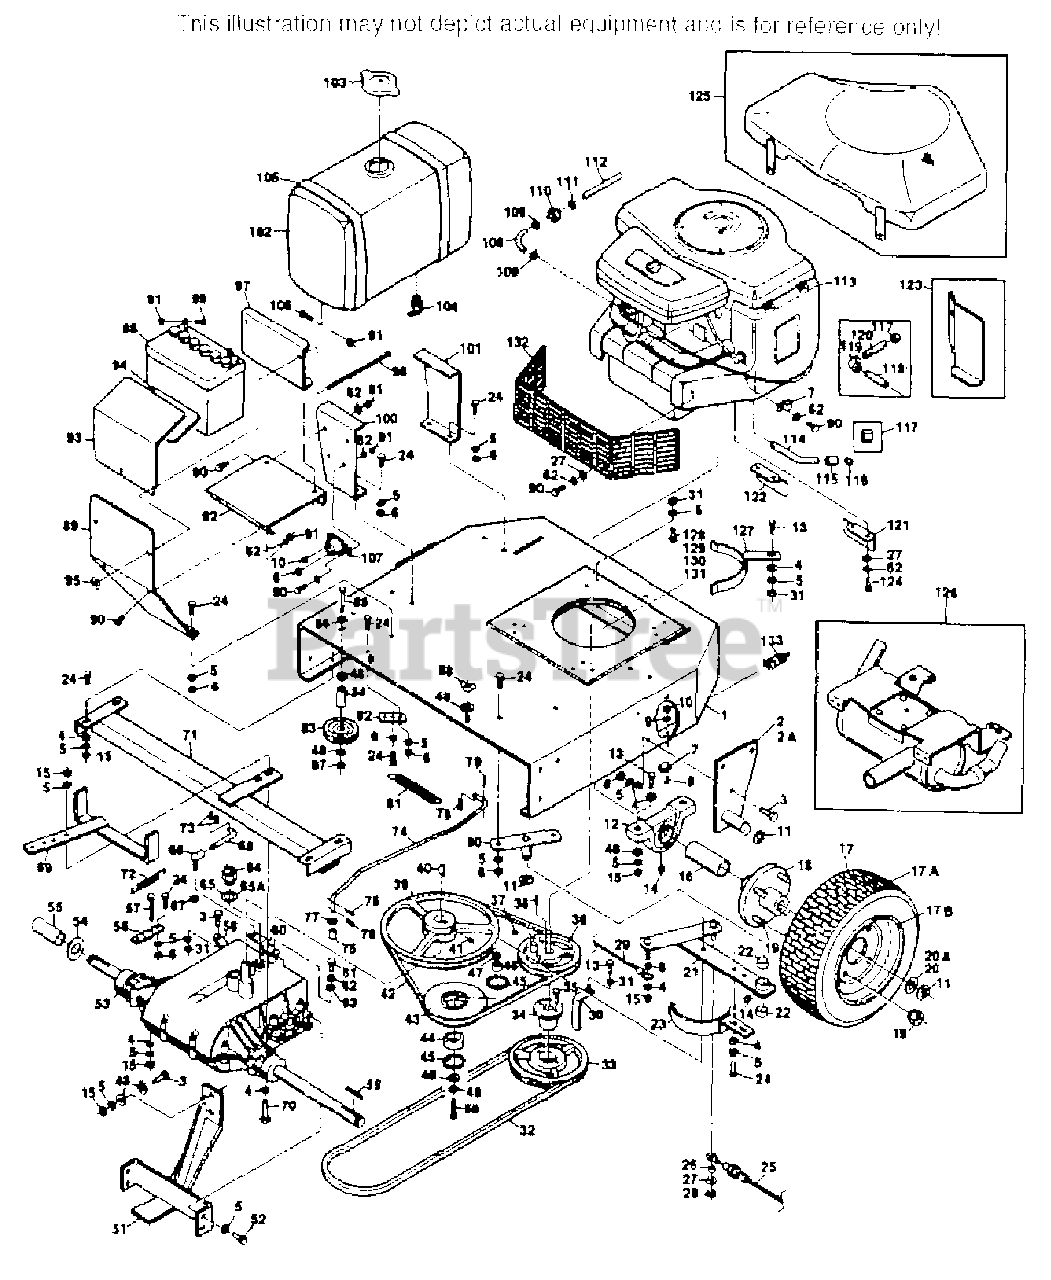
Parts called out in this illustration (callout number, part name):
2	HITCH BRACKET WLD. - RH
2A	HITCH BRACKET WLD. - LH
4	WASHER, 11/32 X 11/16 X 16 GA.
7	CLAMP
9	LOCKWASHER, #10 EXT TOOTH
11	RETAINING RING, 3/4 EXT."E"
12	BEARING, PILLOW BLOCK
14	GREASE FITTING, STR., 1/4-28
17	DRIVE WHEEL ASSEMBLY(INCL. 17A-19)
17A	TIRE, 16 X 6.50-8, 2-PLY
17B	RIM
18	HUB & FLANGE WLD.(INCL. BOLTS)
19	BOLT AND NUT
20	WASHER, 49/64 X 1-1/4 X 16 GA.
20A	WASHER, 13/16 X 1-3/8 X 3/32
21	IDLER ARM WILD.(INCL. 14 & 22)
22	BRONZE BEARING
23	BELT GUIDE WLD.
26	SLEEVE, FOOT CABLE
27	WASHER, 9/32 X 5/8 X 16 GA.
31	HEX NUT, 5/16-18, ELASTIC STOP
33	PULLEY(INCL. 34 & 35)
34	TAPER HUB
36	PULLEY
37	SET SCREW, HEX SOCKET CUP PT.,
38	KEY, 1/4 X 1/4 X 2-1/2
39	PULLEY, TRANSAXLE
40	KEY, WOODRUFF #9
43	PULLEY, IDLER
44	BEARING
45	RETAINING RING, 1-9/16 INT. BASIC
46	SLEEVE
47	SPACER
48	WASHER, 25/64 X 15/16 X 12 GA.
54	THRUST WASHER
56	SPACER, TRANSAXLE
59	KEY, 3/16 X 3/16 X 2-1/2
60	SHIFT LEVER
61	HEX HD. BOLT, 1/4-28 X 3/4 GRD. 8
63	WASHER, 17/64 X 7/8 X 1/8 H.T.
64	NEUTRAL SAFETY SWITCH
65	FIBER WASHER, .010
65A	FIBER WASHER, .020
66	BALL JOINT
67	HEX LOCK NUT, 3/8-24
68	SHIFT CONNECTOR ROD
72	SPRING, BRAKE RETURN
73	HAIR PIN, SMALL
75	SLEEVE
78	HAIR PIN, LARGE
80	PIVOT BASE WLD.
81	SPRING, BELT CLUTCH
82	BRACKET, SPRING MOUNTING
83	PULLEY, BRAKE CABLE
84	SPACER, PULLEY
86	WASHER, 13/32 X 1-1/2 X 7 GA.
88	WING NUT, 3/8-16, ELASTIC STOP
92	BATTERY SHELF
93	BATTERY COVER
94	BATTERY COVER PAD
95	WING NUT, 1/4-20, ELASTIC STOP
96	CARRIAGE BOLT, 1/4-20 X 6
97	BATTERY CLAMP
98	BATTERY
102	FUEL TANK
103	FUEL TANK CAP
104	FUEL SHUT-OFF VALVE
105	FUEL TANK STRAP
110	FUEL FILTER
111	FUEL HOSE CLAMP
133	SAFETY SWITCH, BLADE CLUTCH
